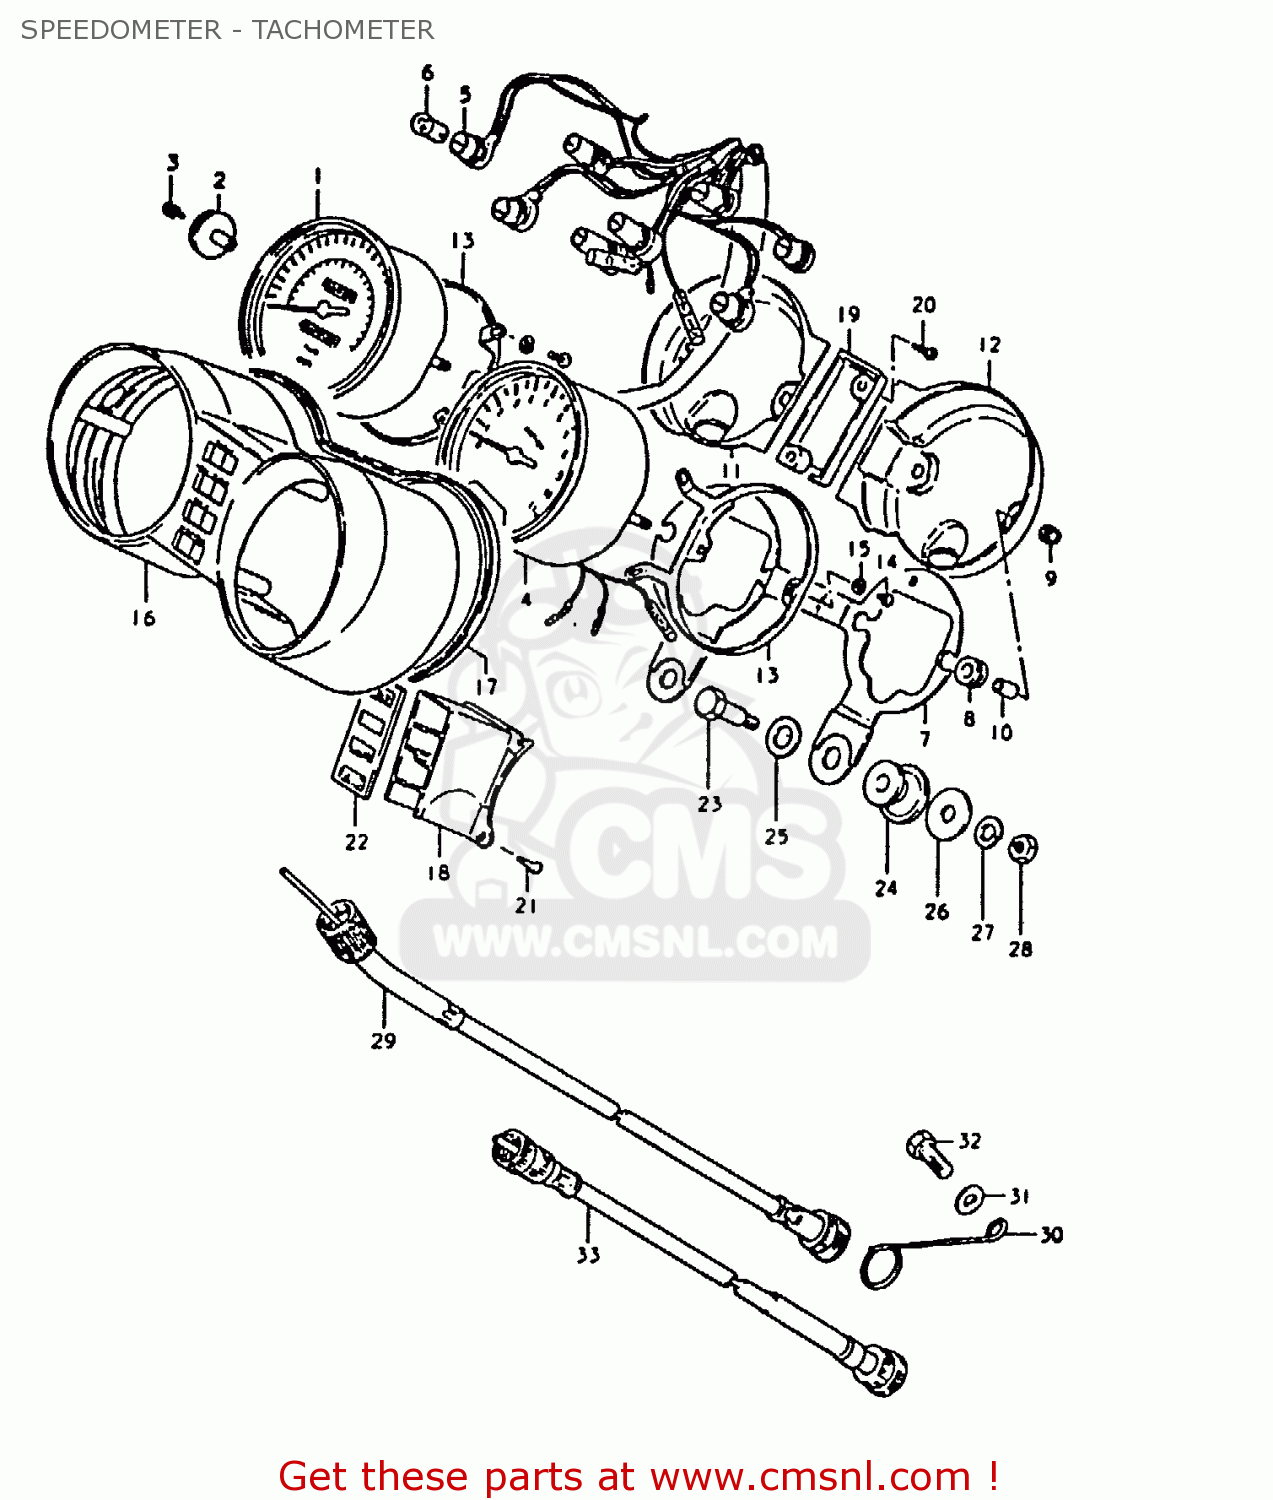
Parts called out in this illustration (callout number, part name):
1	METER,SPEEDOMETER
2	KNOB,TRIP METER
3	SCREW
4	TACHOMETER
5	SOCKET,SPEEDOMETER
6	BULB(12V3.4W,STANLEY,A72A)
7	BRACKET,COMBINATION METER
8	CUSHION,SPEEDOMETER
9	NUT
10	SPACER,SPEEDOMETER
11	COVER,METER,UNDER
12	PLATE,TACHOMETER UNDER
13	HOLDER,METER
14	SCREW
15	LOCK WASHER
16	CASE,METER
17	CUSHION,METER CASE
18	CASE,PILOT BULB
19	PLATE,PILOT BULB CASE
20	SCREW,PILOT CASE
21	SCREW,SPEEDOMETER
22	LENS SET,PILOT LAMP
23	BOLT
24	CUSHION,METER
25	WASHER
26	WASHER (8.5X29X1.6)
27	LOCK WASHER
28	NUT
29	CABLE ASSEMBLY,SPEEDOMETER
30	CLAMP,SPEEDOMETER CABLE
31	WASHER
32	BOLT, UPPER
33	CABLE ASSEMBLY,TACHOMETER
